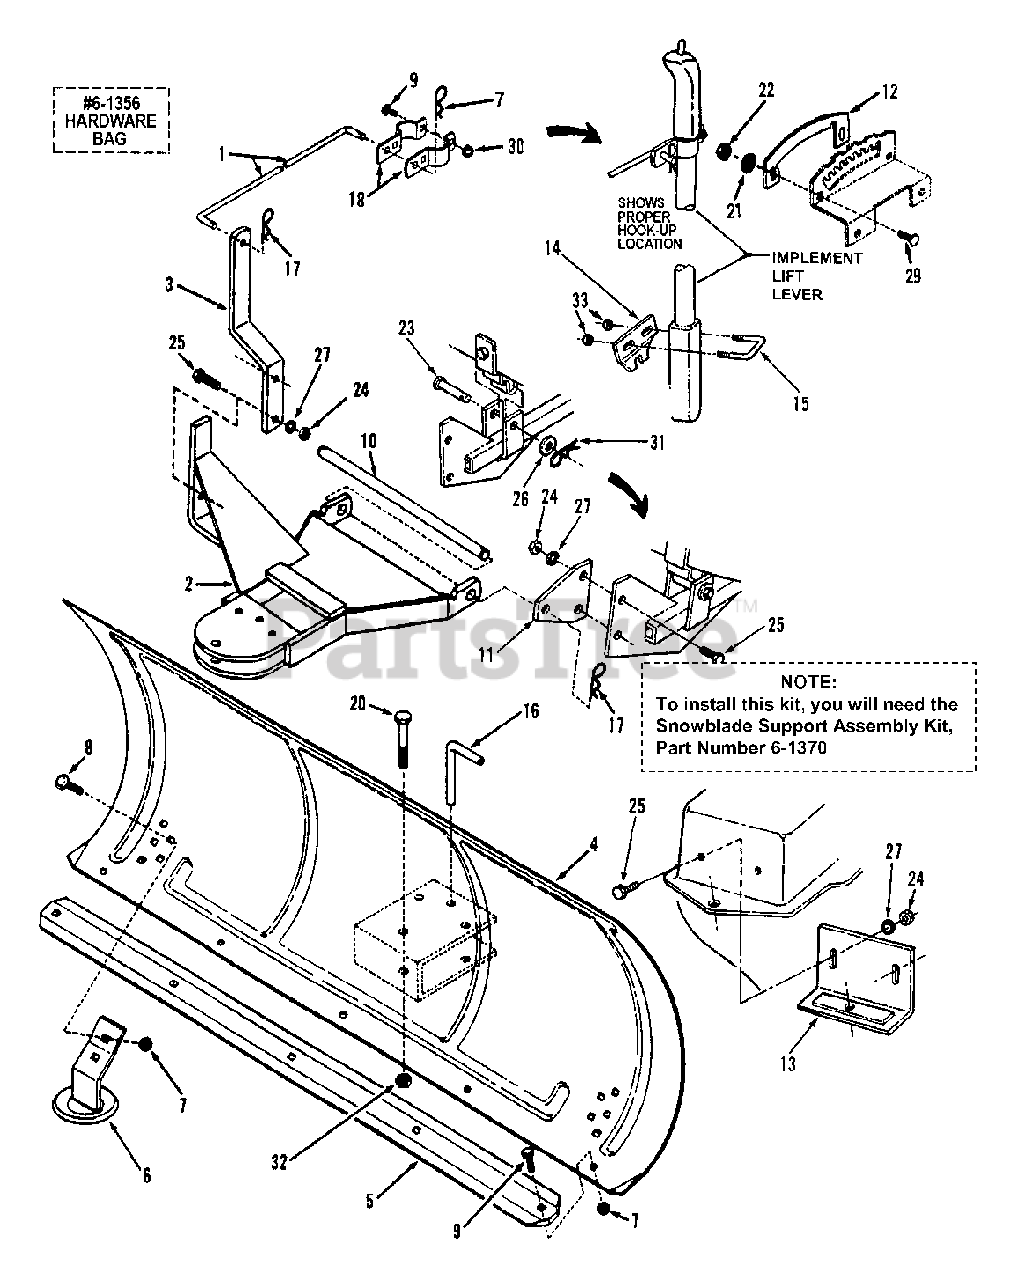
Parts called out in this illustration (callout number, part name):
1	ROD, Lift
2	WELDMENT, Bracket, 36/42 Snow Blade
3	EXTENSION, Lift, 36/42 Snow Blade
4	WELDMENT, 42" Blade
5	SCRAPER
6	WELDMENT, Slide
7	NUT, 3/8-15 Hex Center Lock, Grade 5 or B
8	BOLT, 3/8-16 x 1" Square Neck Carriage, Grade 2
9	BOLT, 3/8-16 x 3/4" Short Neck Carriage, Grade 2
10	PIN, Holding
11	BRACKET, Mount
12	DETENT, High Lockout
13	WELDMENT, Frame Reinforcement
14	BRACE, Latch (Snow)
15	U-BOLT, 5/16-18
16	PIN
17	HAIR PIN, 3/32 x 1-1/8"
18	TAB, Lift Lever
20	SCREW, 1/2-20 x 2-3/4" Hex Head Cap, Grade 5
21	WASHER, 1/4" Internal Tooth Lock
22	NUT, 1/4-20 Hex
23	PIN, 1/2" x 2" Clevis
24	NUT, 3/8-16 Hex
25	SCREW, 3/8-16 x 1" Hex Head Cap, Grade 5
26	WASHER, 1/2" SAE Flat
27	WASHER, 3/8" Internal Tooth Lock
29	BOLT, 1/4-20 x 5/8"
30	NUT, 1/4-20 Hex Flange Lock
31	HAIR PIN, 3/32"
32	NUT, 1/2-20 Hex Center Lock
33	NUT, 5/16-18 Hex Center Lock, Grade B
